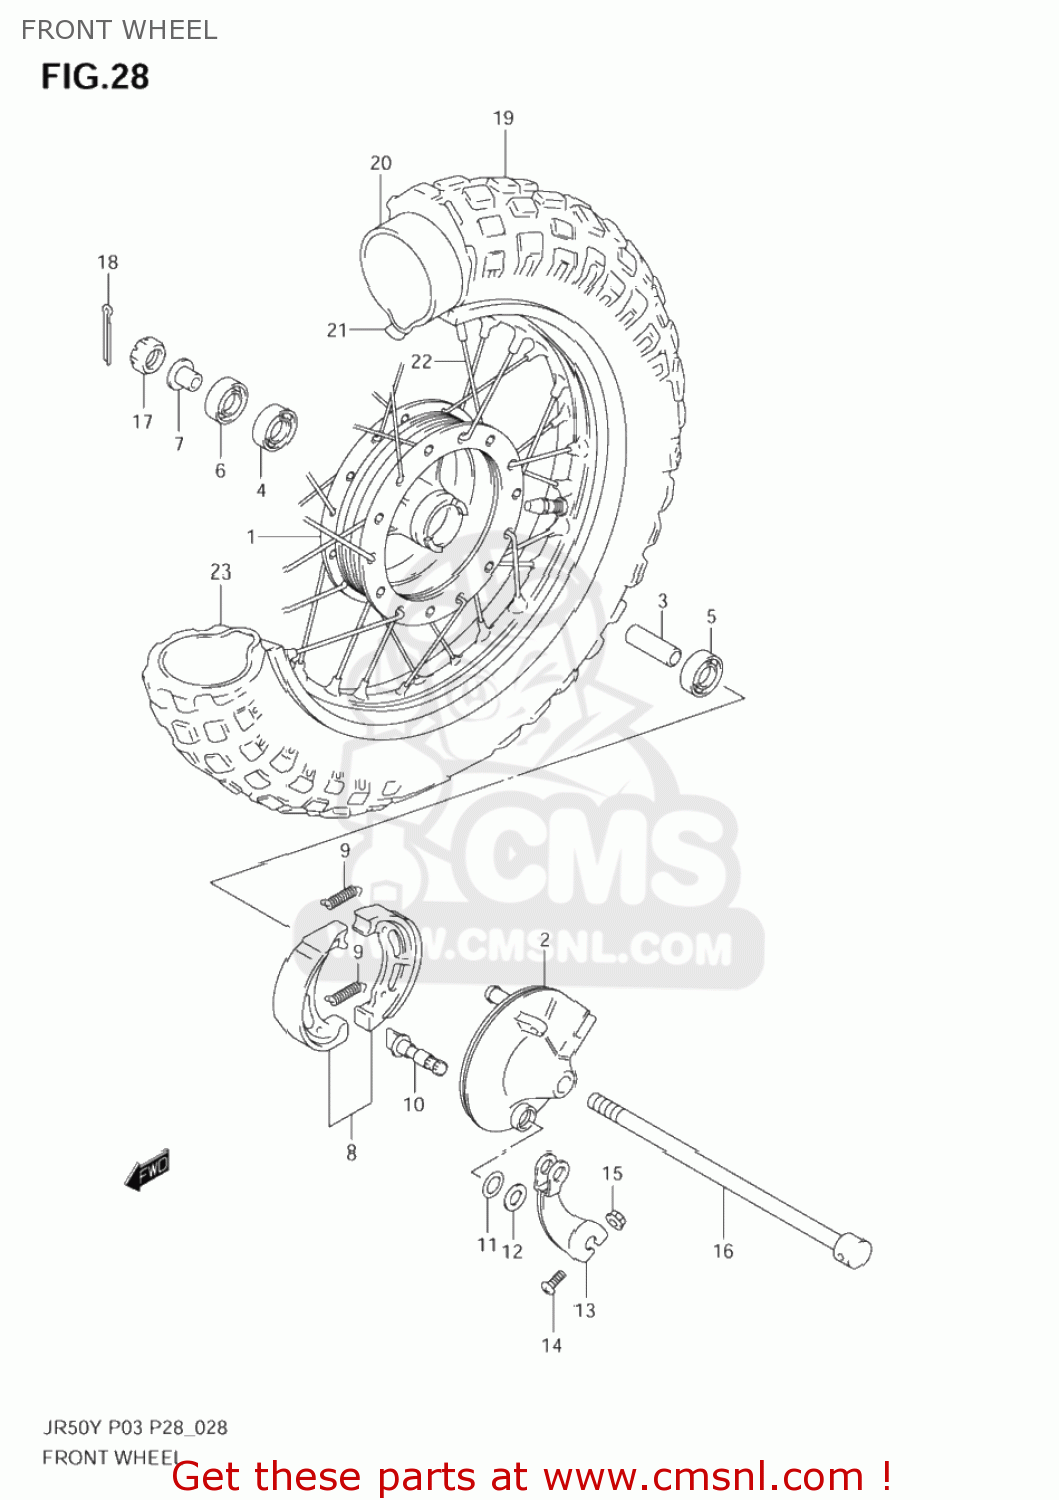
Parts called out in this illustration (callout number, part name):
1	HUB,FR WHEEL
2	PANEL,FR BRAKE ANCHOR
3	SPACER(10.2X16X47)
4	BEARING(10X26X8)
5	BEARING
6	SEAL,OIL(15X27X6)
7	SPACER,AXLE
8	SHOE & SPRING SET (NAS)
9	SPRING(L:35.8)
10	CAM,BRAKE
11	O RING(D:2.4,ID:9.6)
12	WASHER(10.5X18X1)
13	LEVER,FR BRAKE CAM
14	SCREW
15	NUT
16	AXLE,RR
17	NUT
18	PIN 20X20
19	TIRE
20	TUBE,INNER
21	PROTECTOR,INNER TUBE
22	SPOKE SET,RR
23	RIM,WHEEL
